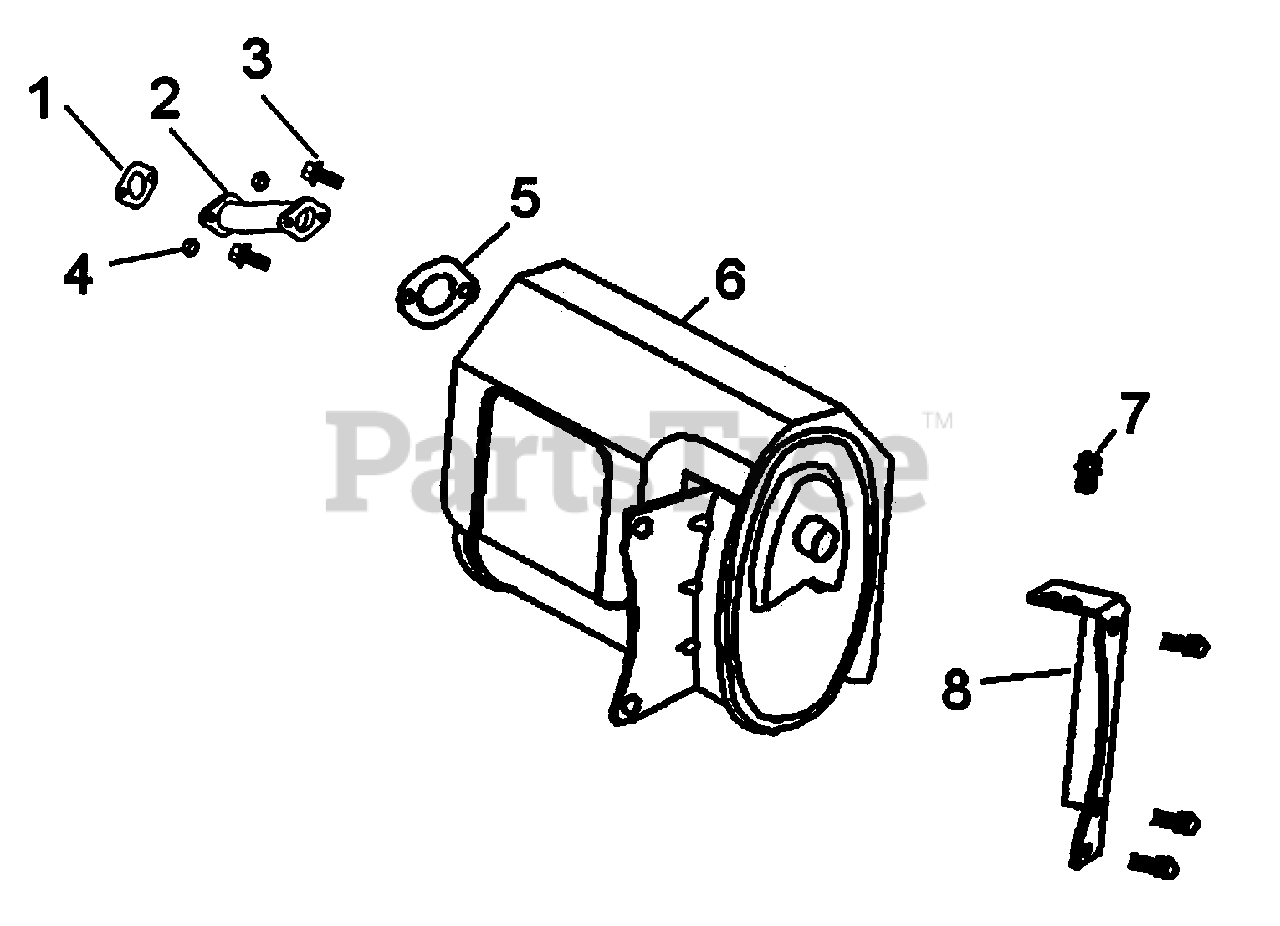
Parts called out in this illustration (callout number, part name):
1	GASKET, EXAUST,CYLINDER
3	BOLT, FLANGE, 8X25
5	GASKET, EX., PIPE
7	BOLT, FLANGE, 8X16
8	STAY COMP., MUFFLER
